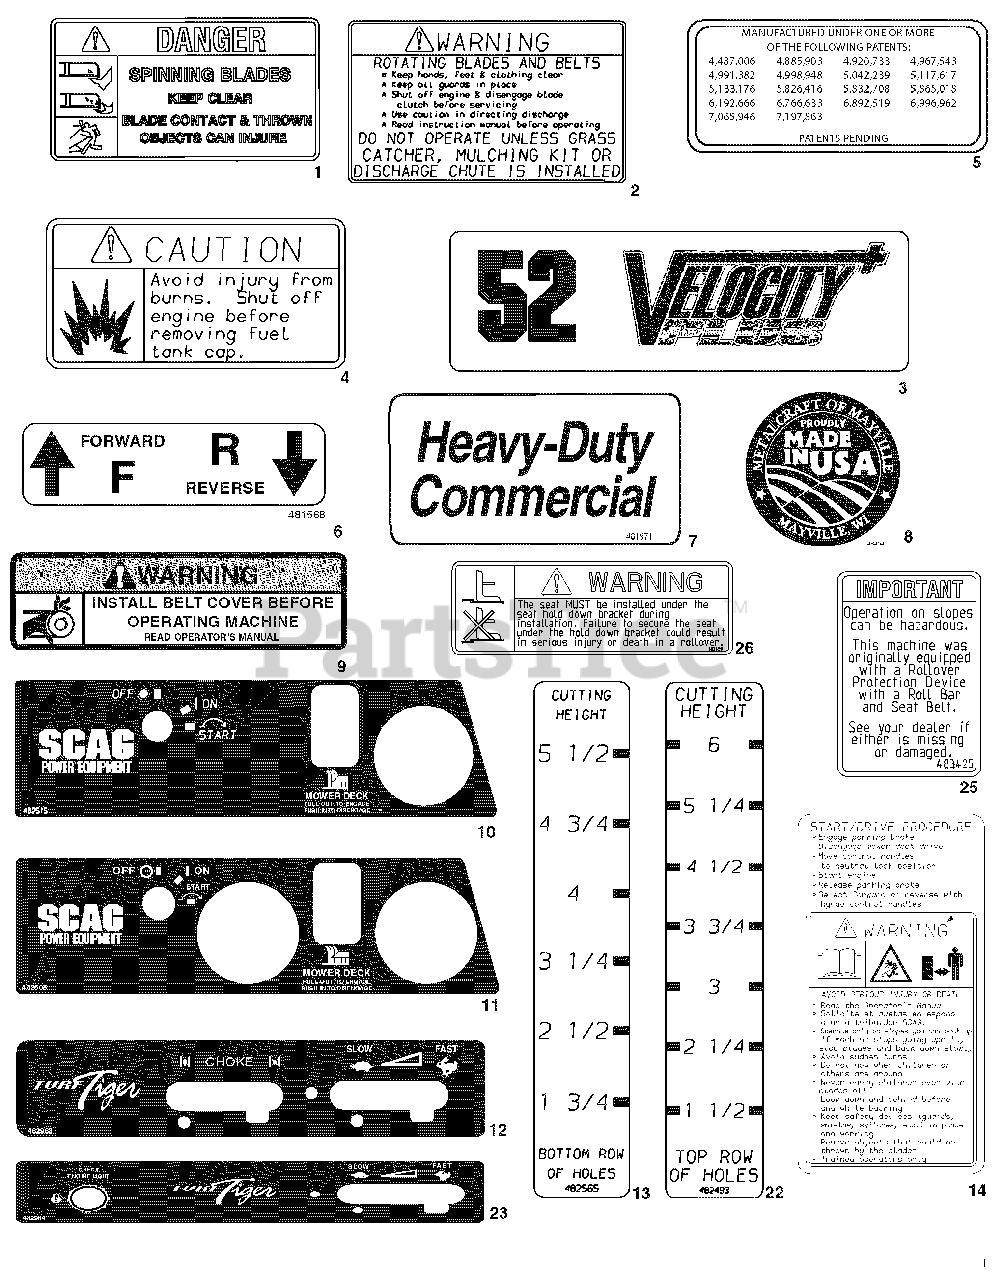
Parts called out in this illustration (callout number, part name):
1	Decal, Danger-Spinning Blades
2	Decal, Warning-Rotating Blades
4	Decal, Fuel Tank
5	Decal, Patents
6	Decal, Traction Control
7	Decal, Heavy Duty Commercial
8	Decal, Metalcraft-Made In USA
9	Decal, Belt Cover
10	Decal, Instrument Panel-Upper
11	Decal, Instrument Panel-Upper
12	Decal, Instrument Panel-Lower
13	Decal, Cutting Height - Lower
14	Decal, Start/Drive Procedure
22	Decal, Cutting Height - Upper
23	Decal, Instrument Panel - Lower
25	Decal, ROPS
26	Decal, Warning Seat Hold Down
